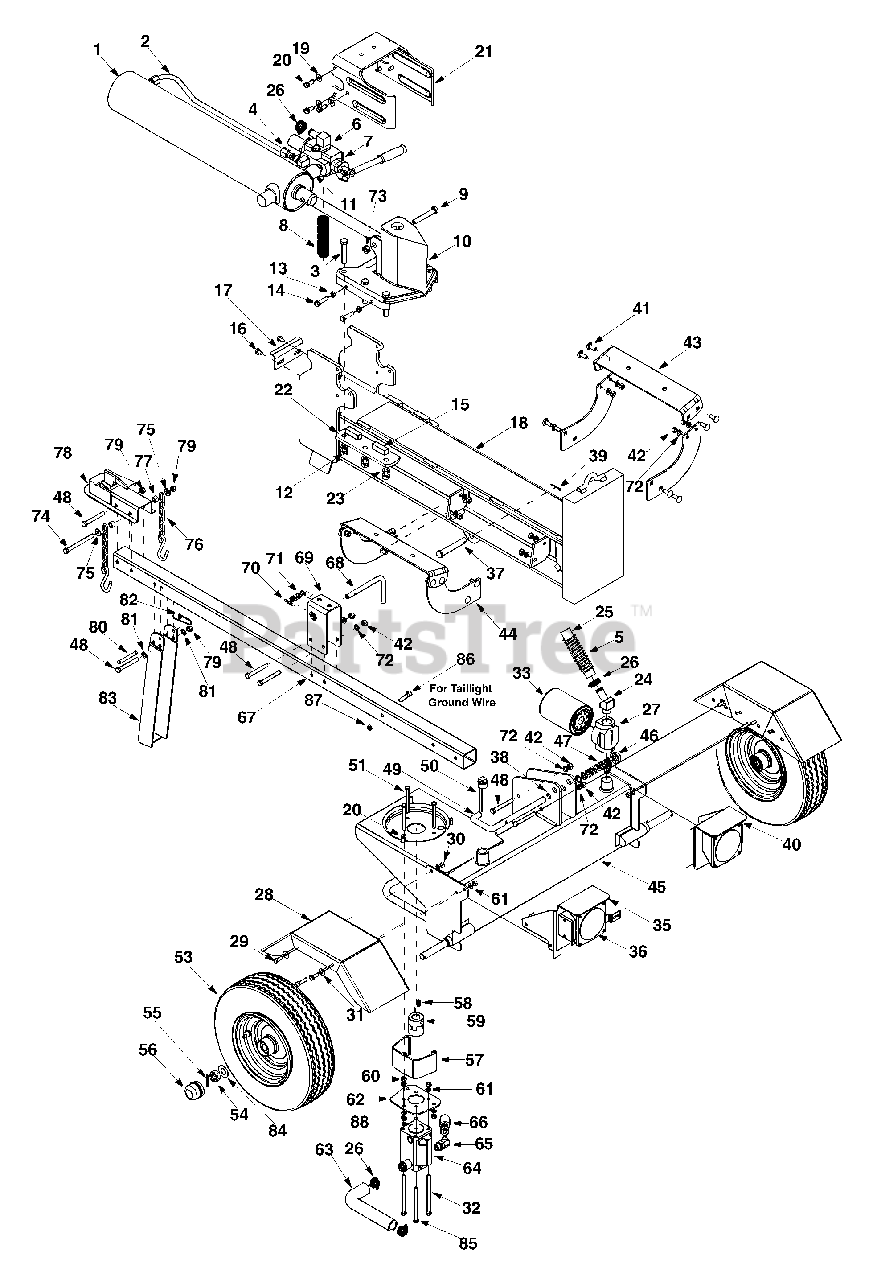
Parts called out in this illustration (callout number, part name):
1	Hydraulic Cylinder
2	Hydraulic Tube
3	Hex Cap Screw 1/2-20 x 2.75
4	90 Degree Solid Adapter
5	Hose Guard
6	Return Elbow
8	Hose Guard
9	Hex Cap Screw 1/2-13 x 3.25
10	Wedge Assembly
11	Nipple Pipe 1/2-14
12	Lock Nut 1/2-20
13	Hex Jam Nut 3/8-24
14	Hex Cap Screw 3/8-24 x 1.5
15	Adjustable Gib
16	LD Screw 5/16-18 x.75
19	Flat Washer.406 ID x.875 OD
20	Hex Washer Screw 3/8-16 x 1.0
23	Lock Washer 1/2
24	Adapter 3/4-14
25	Return Hose 3/4" ID x 44" Lg.
26	Hose Clamp 5/8"
27	Filter Housing
29	Hex Screw
30	Hex Nut 5/16-18
31	Lock Washer 5/16
32	Hex Bolt 5/16-24 x 5.25"
33	Oil Filter
36	Taillight Kit
37	Clevis Pin
38	Flat Washer.635 ID x.93 OD
39	Cotter Pin
41	Carriage Bolt 3/8-16 x 1.0
42	Hex Nut 3/8-16
47	Compression Spring
48	Hex Bolt 3/8-16 x 3"
50	Vented Dipstick
51	Hex Screw 5/16-24 x 3.25
53	Wheel Assembly
54	Slotted Nut 3/4-16
55	Cotter Pin
57	Coupling Shield
58	Square Key 3/16" x.75
59	Flexible Coupling .875 x .437 ID "Stamped L075"
59	Flexible Coupling .750 x .500
59	Flexible Coupling .875 x .500
60	Hex Nut 5/16-24
61	Lock Washer 5/16" ID
64	Gear Pump (11gpm)
64	Pump Kit
64	Gear Pump (9.5 gpm)
65	45 Degree Elbow
66	High Pressure Hydraulic Hose
68	Tongue Latch Rod
70	Spiral Pin
71	Compression Spring
72	L-Washer 3/8"
73	Hex Lock Nut 1/2-13
74	Hex Cap Screw 3/8-16 x 4.25
75	Flat Washer.385 ID x.870 OD
76	Chain
77	Spacer.375 ID x.625 OD
78	Hitch Coupler
79	Hex Lock Nut 3/8-16
80	Clevis Pin
81	Flat Washer.375 ID x.738 OD
82	Spring Pin
85	Hex Bolt 5/16-18 x 4.5"
86	Hex Screw, 5/16-18 x 1.25
87	Jam Nut, 3/8-16
